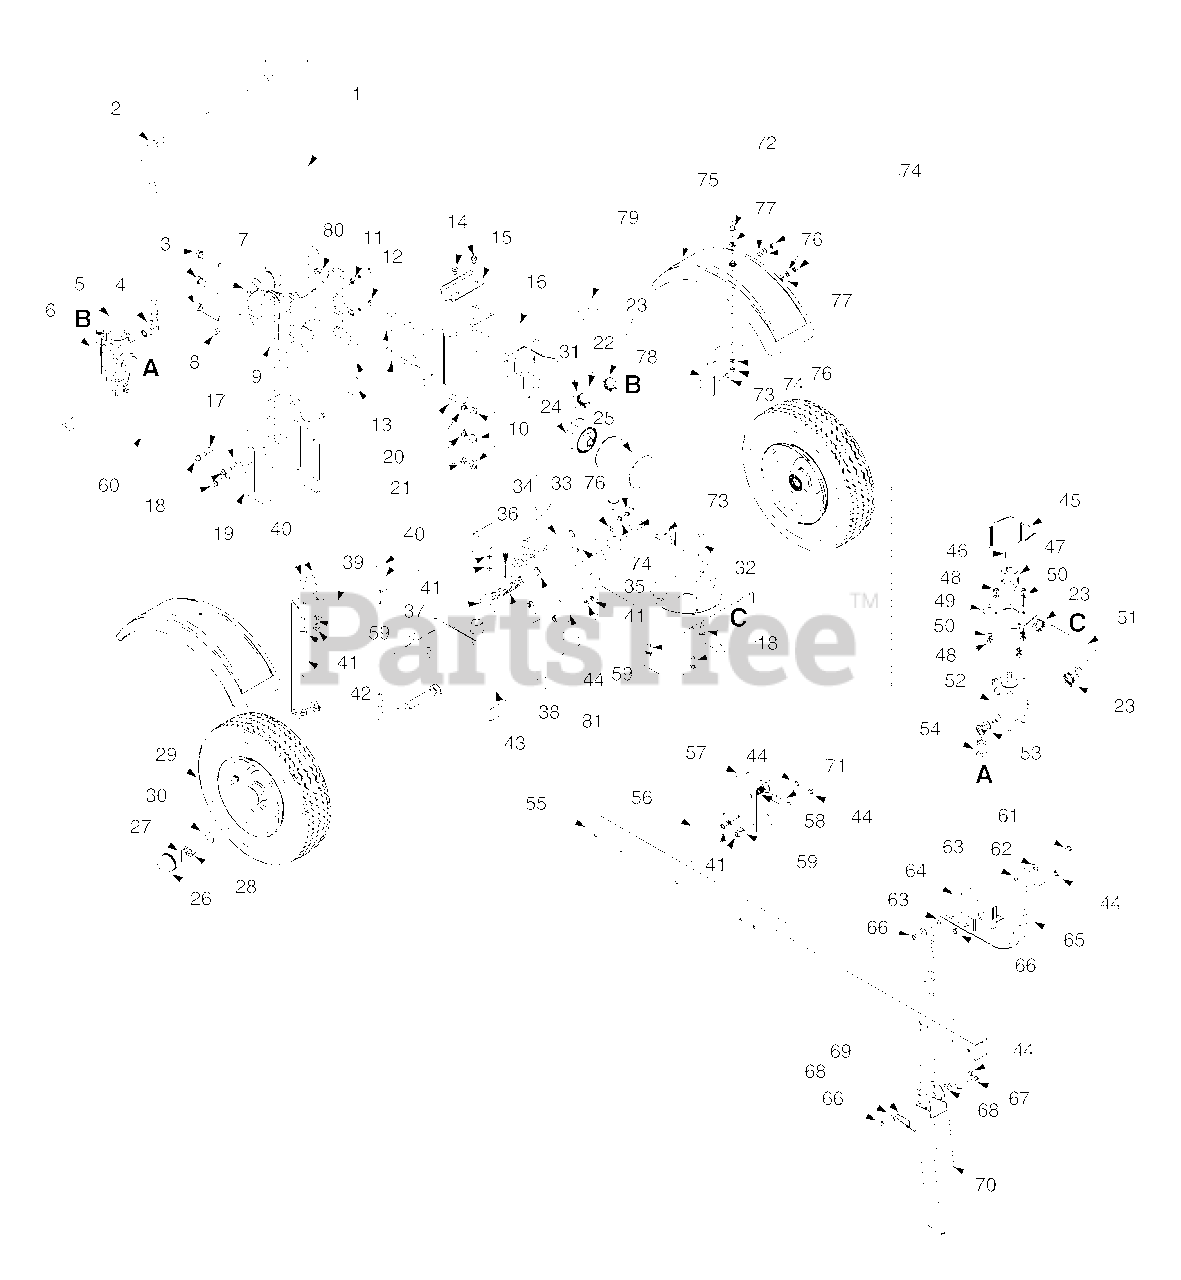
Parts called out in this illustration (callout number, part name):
1	Hydraulic Cylinder
2	Hydraulic Tube
3	Hex Cap Screw 1/2-20 x 2.75
4	90 Degree Solid Adapter
6	Return Elbow
7	Nipple Pipe 1/2-14
8	Hex Cap Screw 1/2-13 x 3.25
9	Wedge Assembly
10	Lock Nut 1/2-20
11	Hex Jam Nut 3/8-24
12	Hex Cap Screw 3/8-24 x 1.5
14	LD Screw 5/16-18 x.75
17	Flat Washer .406 ID x.875 OD
18	Hex Washer Screw 3/8-16 x 1.
21	Lock Washer 1/2
22	Return Hose 3/4" ID x 44" Lg.
23	Hose Clamp 5/8"
24	Filter Housing
25	Oil Filter
26	Hub Cap
27	Cotter Pin
28	Slotted Nut 3/4-16
29	Wheel Assembly
30	Flat Washer .760 ID x.500 OD
31	Adapter 3/4-14
32	Hex Screw 5/16-24 x 3.25
33	Vented Dipstick
34	Clevis Pin
35	Lock Rod
36	Cotter Pin
37	Push Cap
38	Compression Spring
41	Hex Nut 3/8-16
43	Frame Assembly
44	Hex Bolt 3/8-16 x 3"
45	Coupling Shield
46	Square Key 3/16" x.75
47	Flexible Coupling .750 x .500
47	Flexible Coupling .875 x .500
47	Flexible Coupling .875 x .437
48	Hex Nut 5/16-24
50	Lock Washer 5/16" ID
52	Gear Pump (11 gpm)
52	Pump Kit
52	Gear Pump (9.5 gpm)
53	45 Degree Elbow Fitting
54	High Pressure Hydraulic Hose
56	Latch Rod
58	Compression Spring
59	L-Washer 3/8"
60	Hose Guard
61	Hex Cap Screw 3/8-16 x 4.25
62	Flat Washer .385 ID x.870 OD
63	Spacer .375 ID x.625 OD
64	Hitch Coupling Assembly
65	Chain
66	Hex Lock Nut 3/8-16
67	Clevis Pin
68	Flat Washer .375 ID x.738 OD
69	Spring Pin
72	Hex Bolt 5/16-18 x 0.875"
73	Hex Bolt 5/16-18 x 0.875"
74	Hex Nut 5/16-18
75	Black Fender
76	Lock Washer
77	Flat Washer
79	Hose Guard
80	Hex Lock Nut 1/2-13
81	Flat Washer .635 x.93 x.06
